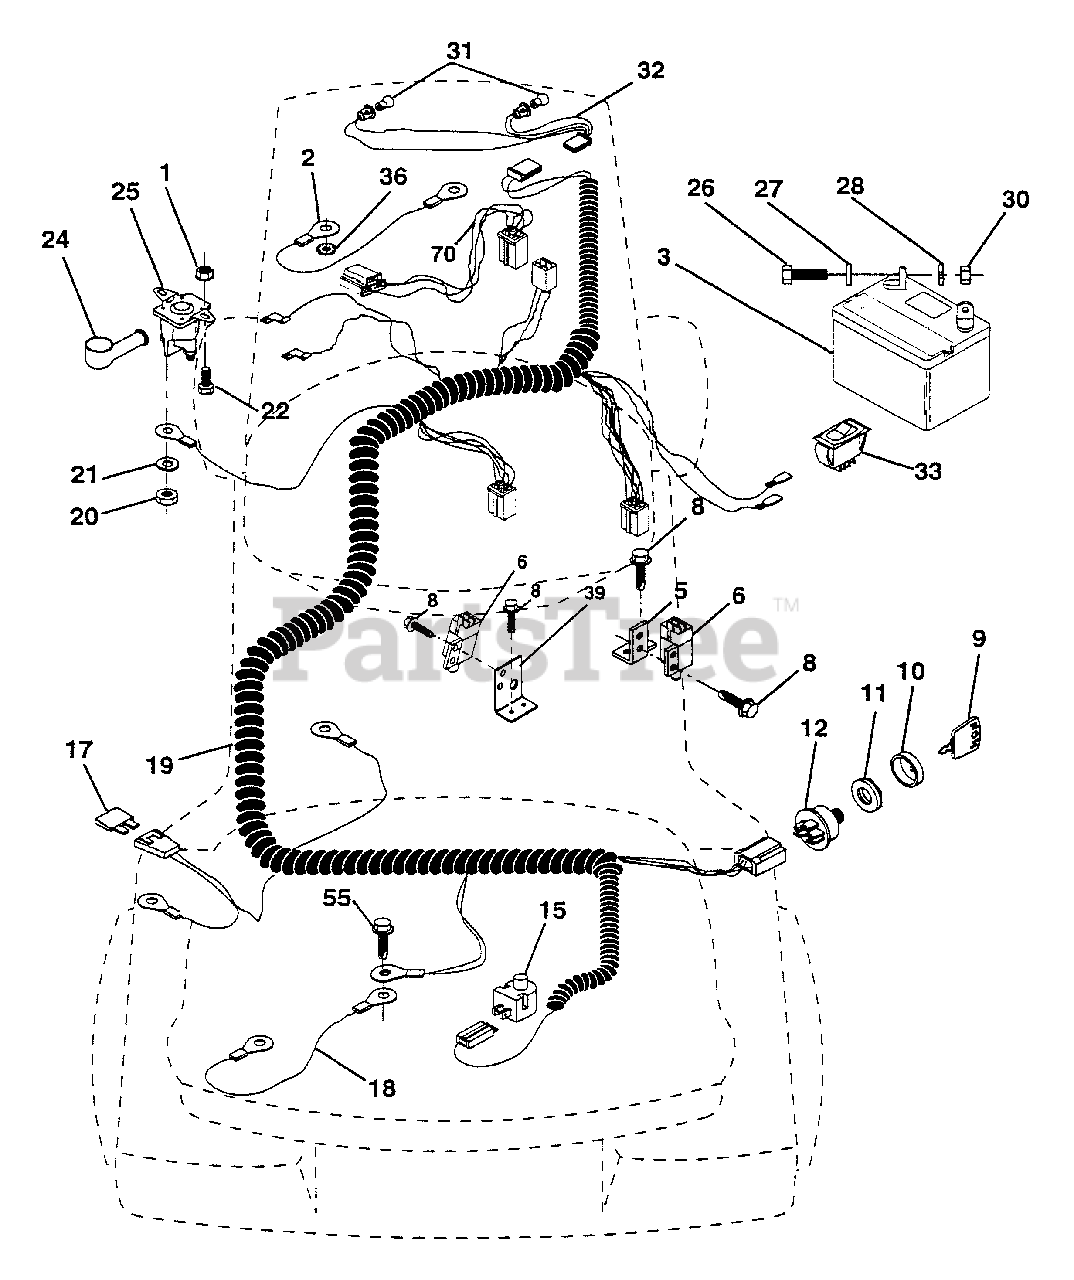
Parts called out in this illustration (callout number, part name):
1	Nut, Hex, Keps 1/4-20
2	Assembly, Cable
3	Battery
5	Bracket, Switch
6	Switch, Interlock, 4 Terminal
8	Screw, Hex Head, Self-Tapping #10-24 x 1/2
9	Key, Molded
10	Cover, Ignition Key
11	Nut, Ignition
12	Switch, Ignition
15	Switch, Plunger
18	Assembly, Cable
19	Harness, Ignition
20	Nut, Hex, Jam 1/4-20
21	Washer, Lock 1/4
22	Bolt, Hex, Fin. 1/4-20 UNC x 1/2 Grade 5
24	Cover, Terminal
25	Solenoid
26	Bolt, Hex Head 1/4-20 UNC x 3/4
27	Washer 9/32 x 5/8 x 16 Gauge
28	Washer, Lock 1/4
30	Nut, Hex, Fin. 1/4-20 UNC
31	Bulb, Light
32	Harness, Headlight
33	Switch, Light
36	Washer, Lock, Internal Tooth 1/4
39	Bracket Switch Clutch
55	Screw Thdrol 5/16 - 18 x 1/2
70	Engine Harness
